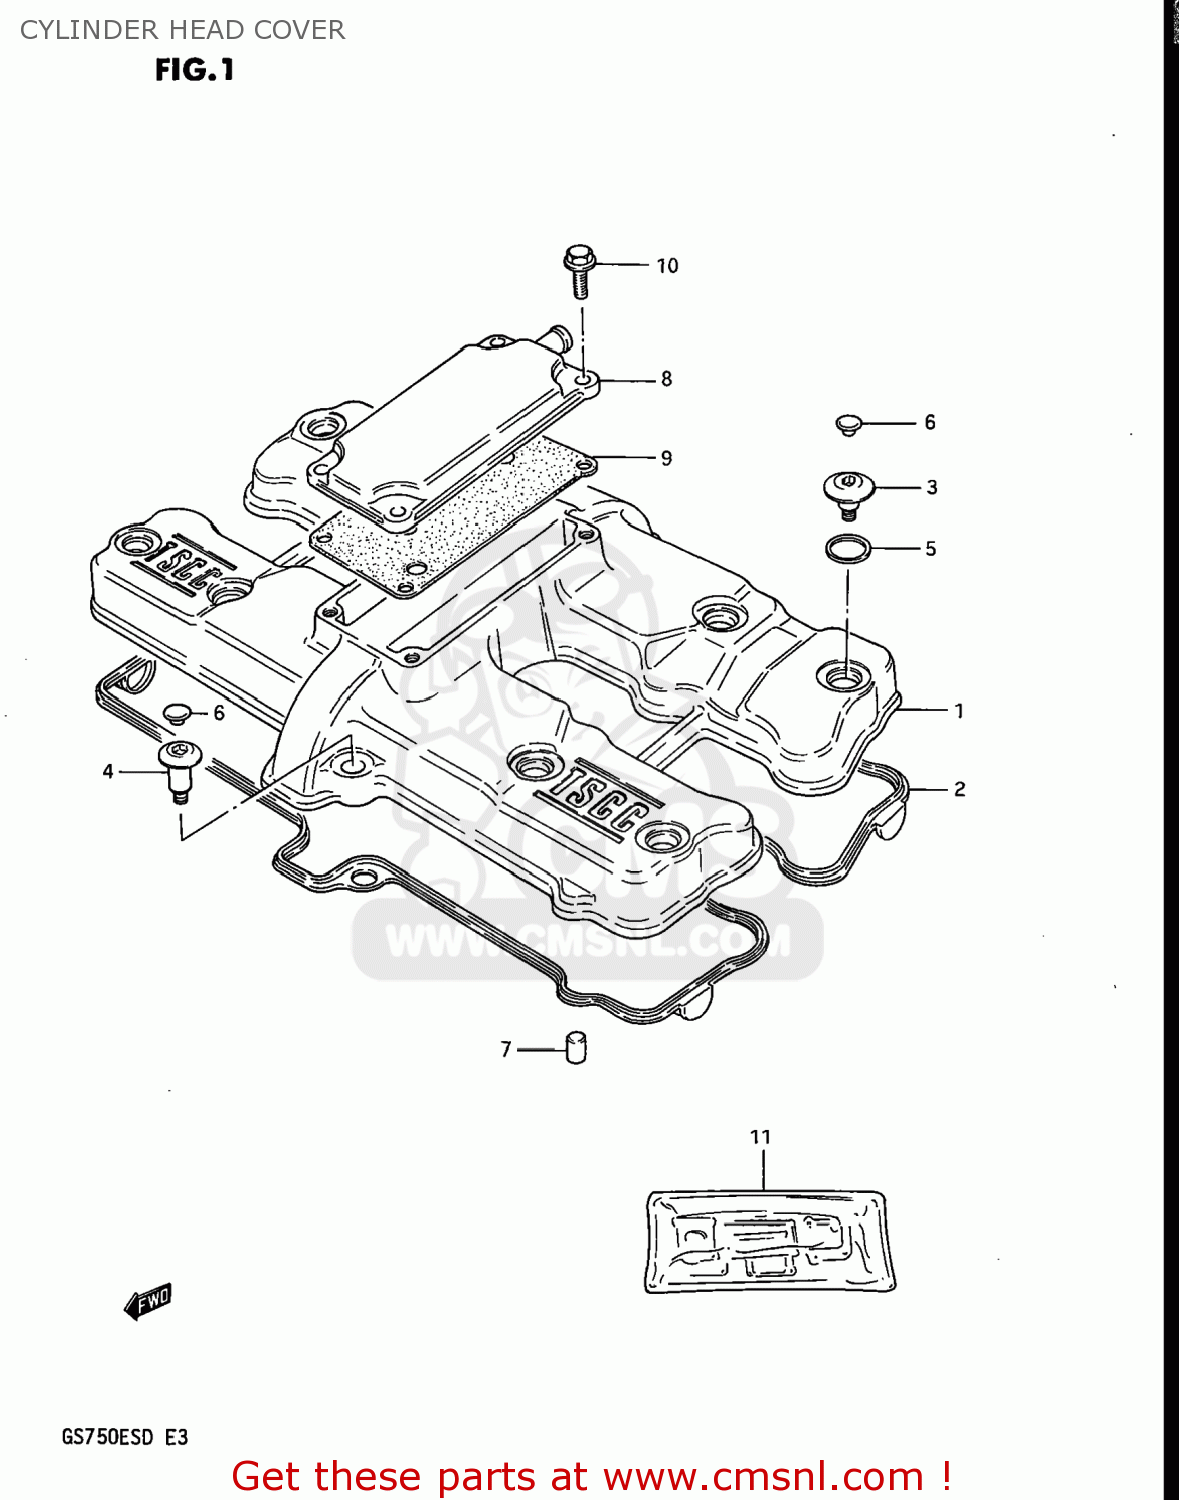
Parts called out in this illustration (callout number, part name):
1	COVER,CYLINDER HEAD
2	GASKET,HEAD COVER (NAS)
3	BOLT(7X5.5)
4	BOLT(7X19)
5	WASHER
6	CAP(OD:10)
7	PIN
8	COVER,BREATHER
9	GASKET (MCA)
10	BOLT,REAR
11	GASKET SET (MCA)
